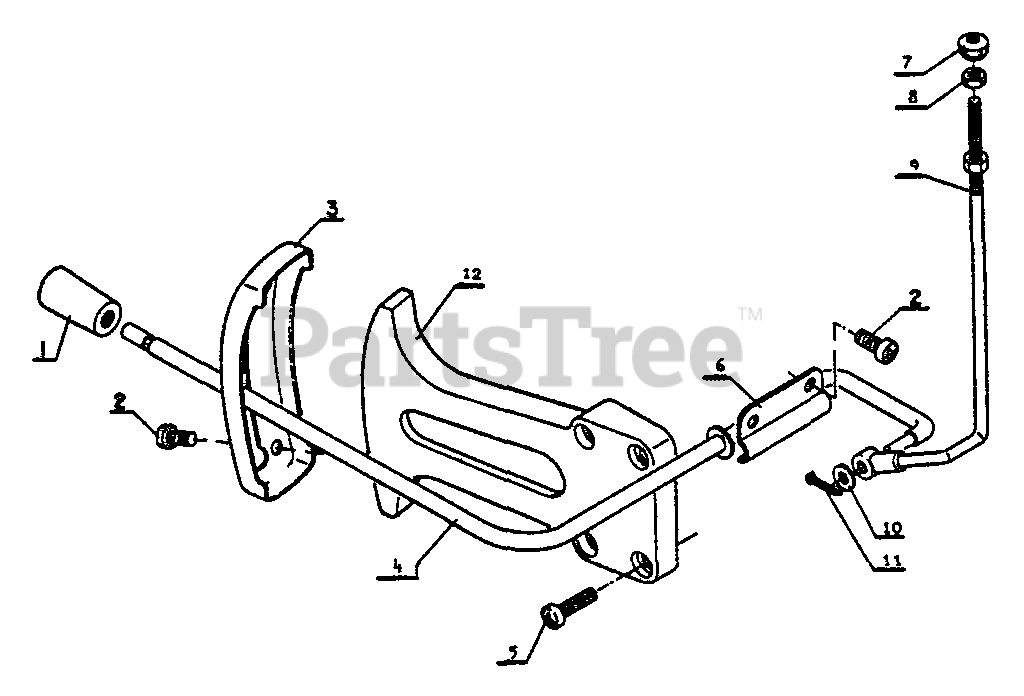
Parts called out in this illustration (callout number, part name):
2	SCREW 5×10
3	DIAL
4	LEVER, THROTTLE
5	SCREW 5×18
6	RETAINER
9	ROD, THROTTLE
10	WASHER 4 MM
11	PIN, COTTER
12	BRACKET, DIAL
